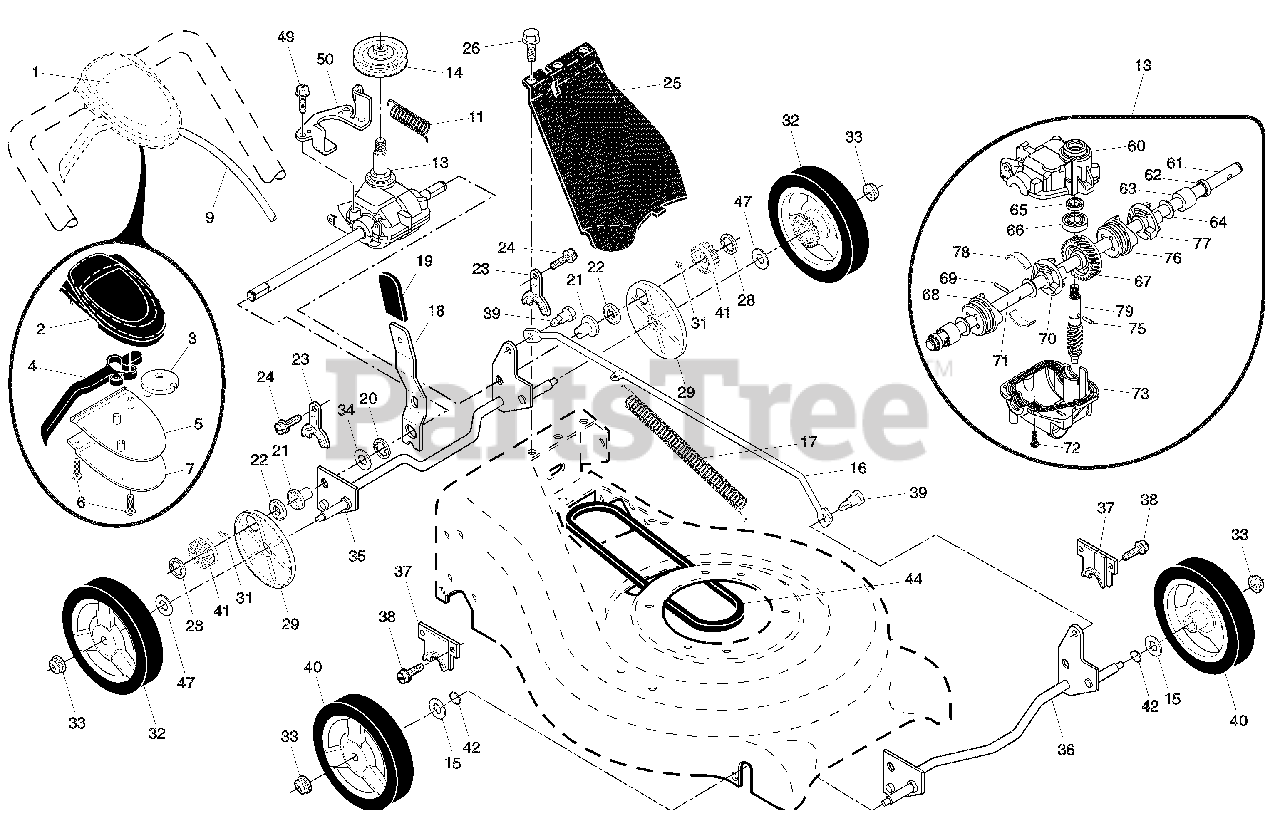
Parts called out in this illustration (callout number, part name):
1	Drive Control Assembly, Auto-Walk
2	Cover, Top, Auto-Walk Drive Control
4	Lever, Auto-Walk Drive Control
5	Cover, Bottom, Auto-Walk Drive Control
6	Screw, Phillips Head #10 x 5/8
7	Plate, Trigger, Auto-Walk Drive Control
9	Cable, Drive Control
11	Spring, Return
13	Gear Case Assembly
14	Pulley, Drive
15	Washer, Flat
16	Rod, Connecting
17	Spring, Extension
18	Spring Selector
19	Knob, Selector Spring
21	Bearing, Support
22	Bearing, Ball
23	Retainer, Drive Assembly, Stamped
24	Screw, Tapping, Hex Head 1/4-20 x 3/4
25	Cover Drive
26	Screw, Threaded, Rolled #10-25 x 1/2
28	E-Ring 7/16
29	Cover, Dust, Wheel
31	Pawl, Drive
32	Wheel & Tire Assembly, Rear
33	Nut, Hex, Flangelock 3/8-16
35	Shaft Assembly, Rear
36	Shaft Assembly, Front
37	Retainer, Front Shaft
38	Screw, Hi-Lo Thread #12 x 5/8
39	Bolt, Shoulder, Semi-Gimlet Point
40	Wheel & Tire Assembly, Front 8 x 1-3/4
47	Washer 1/2 x 1-1/2 x .134
49	Screw, Hi-Lo Thread #12 x 5/8
50	Belt Keeper
60	Case, Upper
61	Shaft, Output, Long
62	Seal, Output Shaft
65	Seal, Worm Shaft
66	Bearing, Ball
67	Gear, 28 Teeth
68	Fixed Dog Clutch, LH
69	Pin, Output Shaft
70	Movable Dog Clutch, LH
71	Shaft, Output, Short
72	Screw, Case
73	Case, Lower
75	Pin, Worm Shaft
76	Fixed Dog Clutch, RH
77	Movable Dog Clutch, RH
78	Spring, Leaf
79	Shaft, Worm
